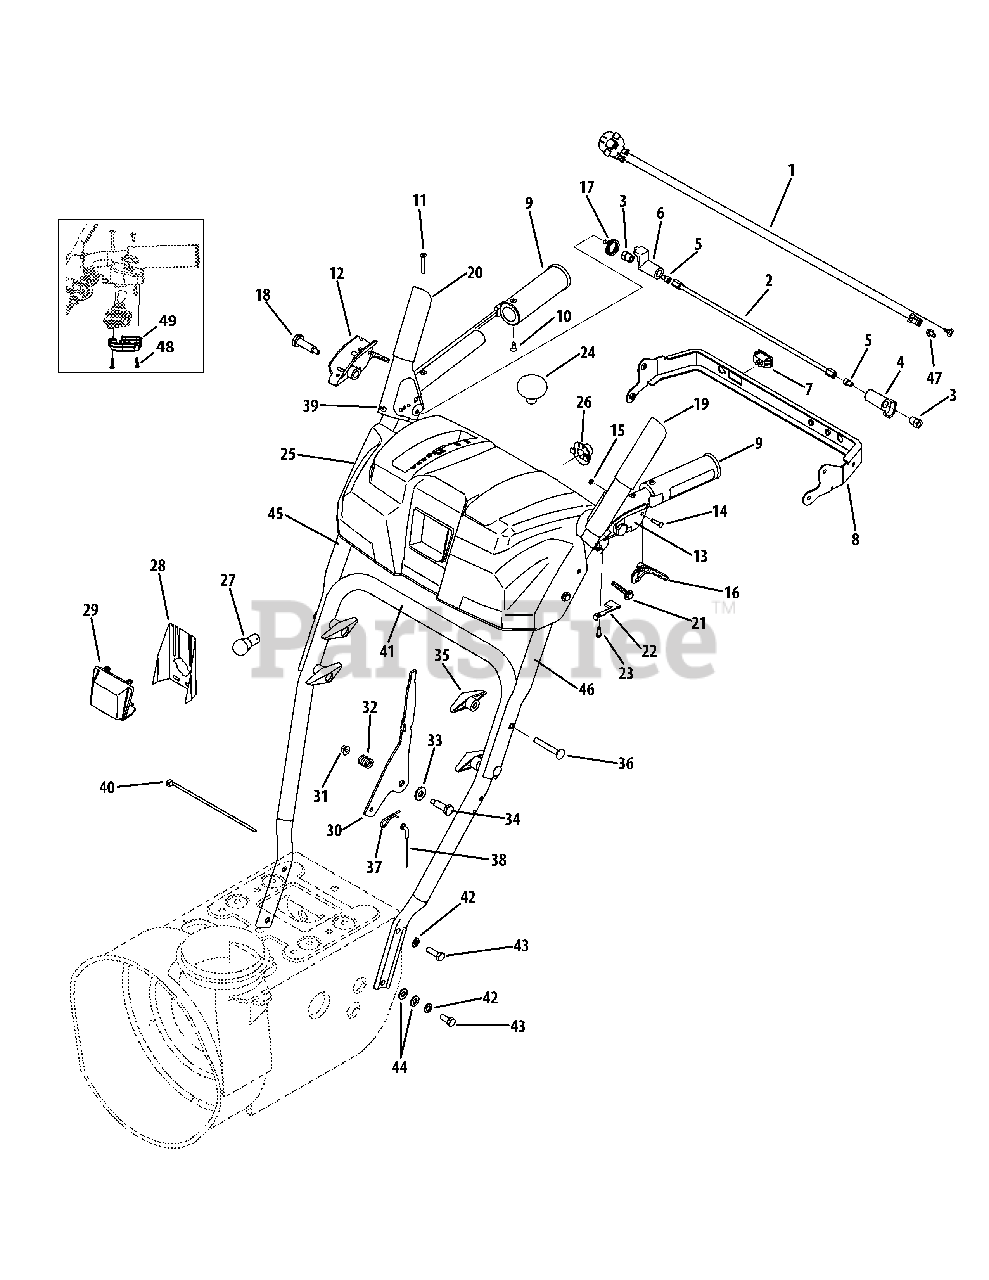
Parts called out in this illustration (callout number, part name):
1	Wire Harness
2	Clutch Lock Rod Assembly
3	Hex Shoulder Nut, 1/4-20
4	Clutch Lock Cam
5	Socket Cap Screw 1/4-20 x .50
7	Heated Grip Switch
8	Panel Bracket
9	Heated Grip
10	AB Screw, #10-16 x .625
11	Machine Screw, #10-24 x 1.375
12	Clutch Lock Handle Assembly, RH
13	Clutch Lock Handle Assembly, LH
15	E-Type Ring, .375
16	Clutch Trigger Lock
17	Torsion Spring, .8156 ID x .3038
18	Shoulder Screw, .437 x 1.345 x 1/4-20
19	Engagement Handle Assembly, LH
20	Engagement Handle Assembly, RH
21	Hex Washer Screw, 1/4-20 x 1.625
22	Clutch Lock Spring
23	Hex Washer Screw, #8-16 x .50
24	Shift Knob
25	Handle Panel
26	Light Socket
28	Lens Label
31	Flange Lock Nut, 1/4-20
32	Compression Spring, .39 x .60 x .88
33	Flat Washer, .385 x .87 x .06
34	Shoulder Screw, .374 x 1.05
35	Wing Knob
36	Carriage Screw, 5/16-18 x 2.25
37	Click Pin, .092 x 1.64
38	Speed Selector Cable
39	Rubber Bumper, .62 x .22
40	Cable Tie, 3/16 x .05 x 7.43
42	Lock Washer, 5/16
43	Hex Bolt, 5/16-18 x .75
44	Flat Washer, .344 x .688 x .065
45	Upper Handle, RH
46	Upper Handle, LH
47	Screw, 1/4-20 x .500
48	Screw, .159 OD x .610
49	Housing Cover (Elec Chute)
